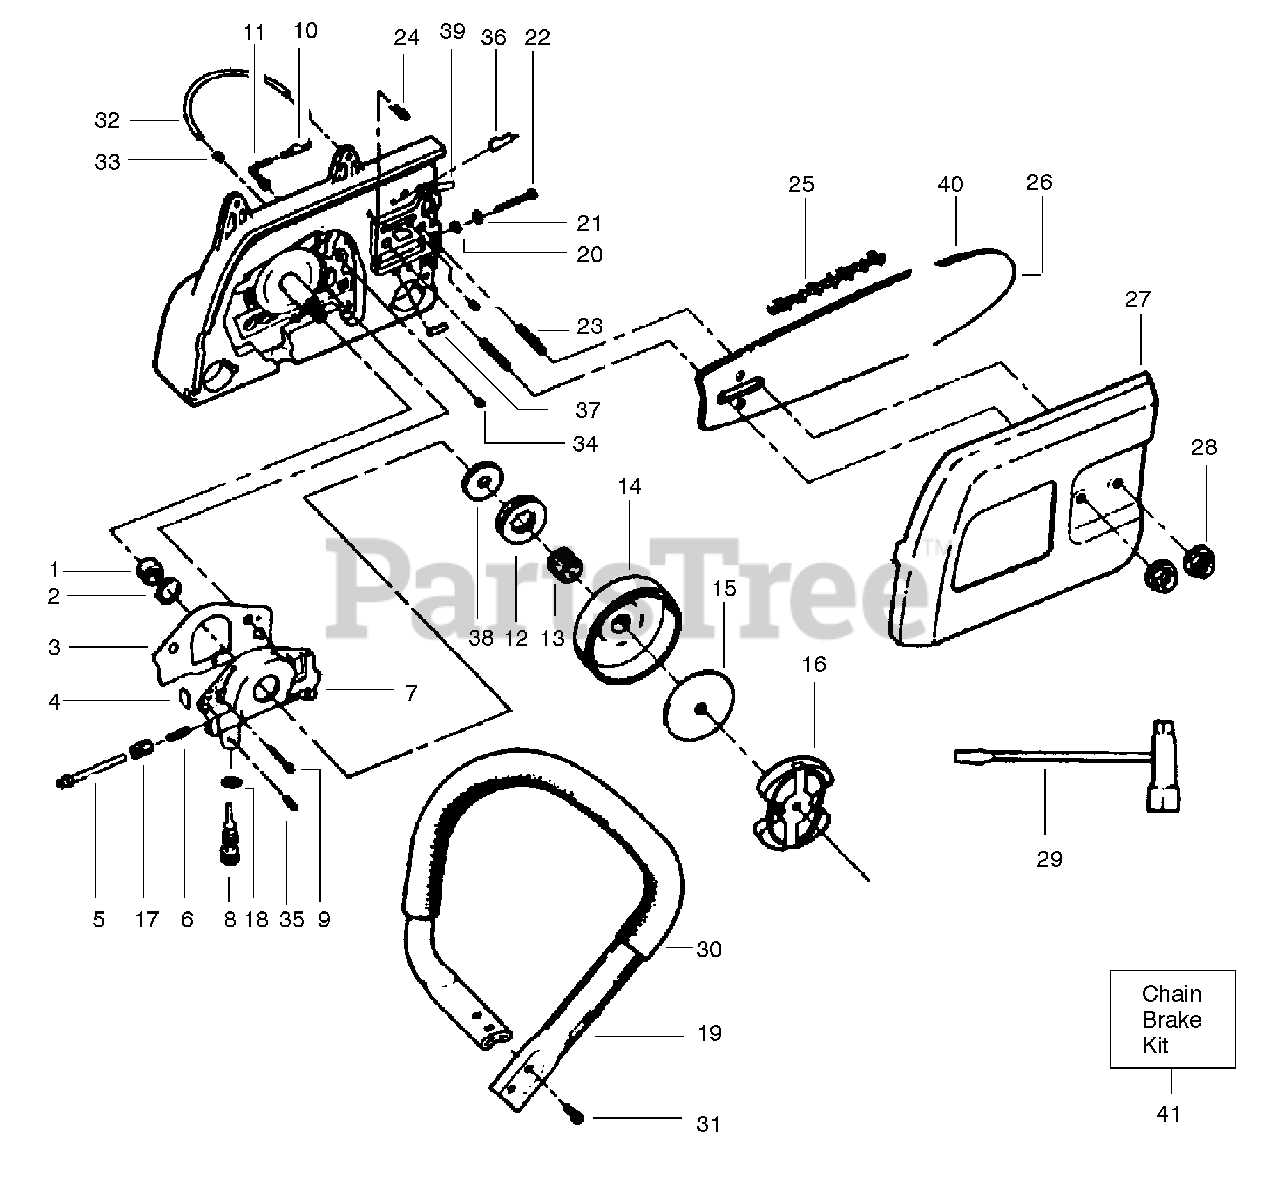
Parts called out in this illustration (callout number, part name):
1	Wire Worm Gear
2	Seal-Oil Pump
3	Engine Gasket Set
4	Dust Plug
5	Shaft Assy
6	Spring-Plunger
7	Oil Pump Kit
8	Screw-Oiler Adjust
9	Screw
10	Oil Pickup & Filter
11	Oiler Intake Line
12	Rim-Floating (3/8 Pitch)
14	Drum & Adaptor Assy
15	Clutch Plate
16	Clutch Ass'y.
17	Gear Spur
18	"O" Ring
19	Handlebar Assy
20	Guide Bar Pin
21	Retainer-Bar Adjust
23	Stud-Guide Bar
24	Cotter Pin
25	Chain-20"
26	Bar-20"
27	Bar Clamp Assy
28	Nut-Bar Mounting
29	Scrench
29	Silver Finish (1/2")
29	Gold Finish (9/16")
30	Handlebar Grip
32	Oiler Discharge Line
33	Oiler Discharge Sleeve
34	Tubing Nut
35	Pin-Adjustment Screw
36	Chain Pad-Top
37	Chain Pad
38	Washer-Thrust
39	Crankcase Plug
40	Replaceable Sprocket Nose
41	Chain Brake Kit
